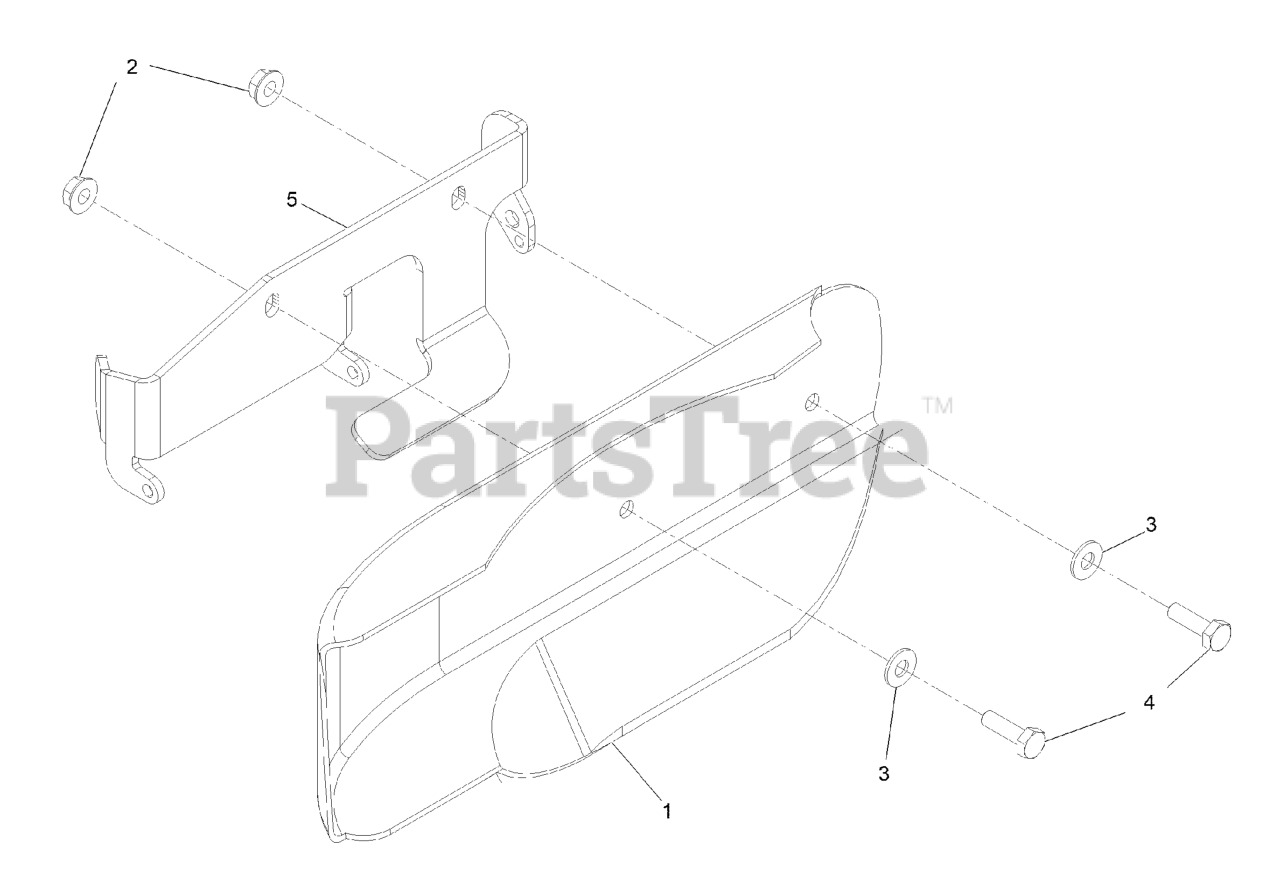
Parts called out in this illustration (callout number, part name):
1	Screw-HH 1/4-20 X 7/8 SS
2	BRACKET-DEFLECTOR, SIDE
3	WASHER-FLAT
4	SCREW-HH
